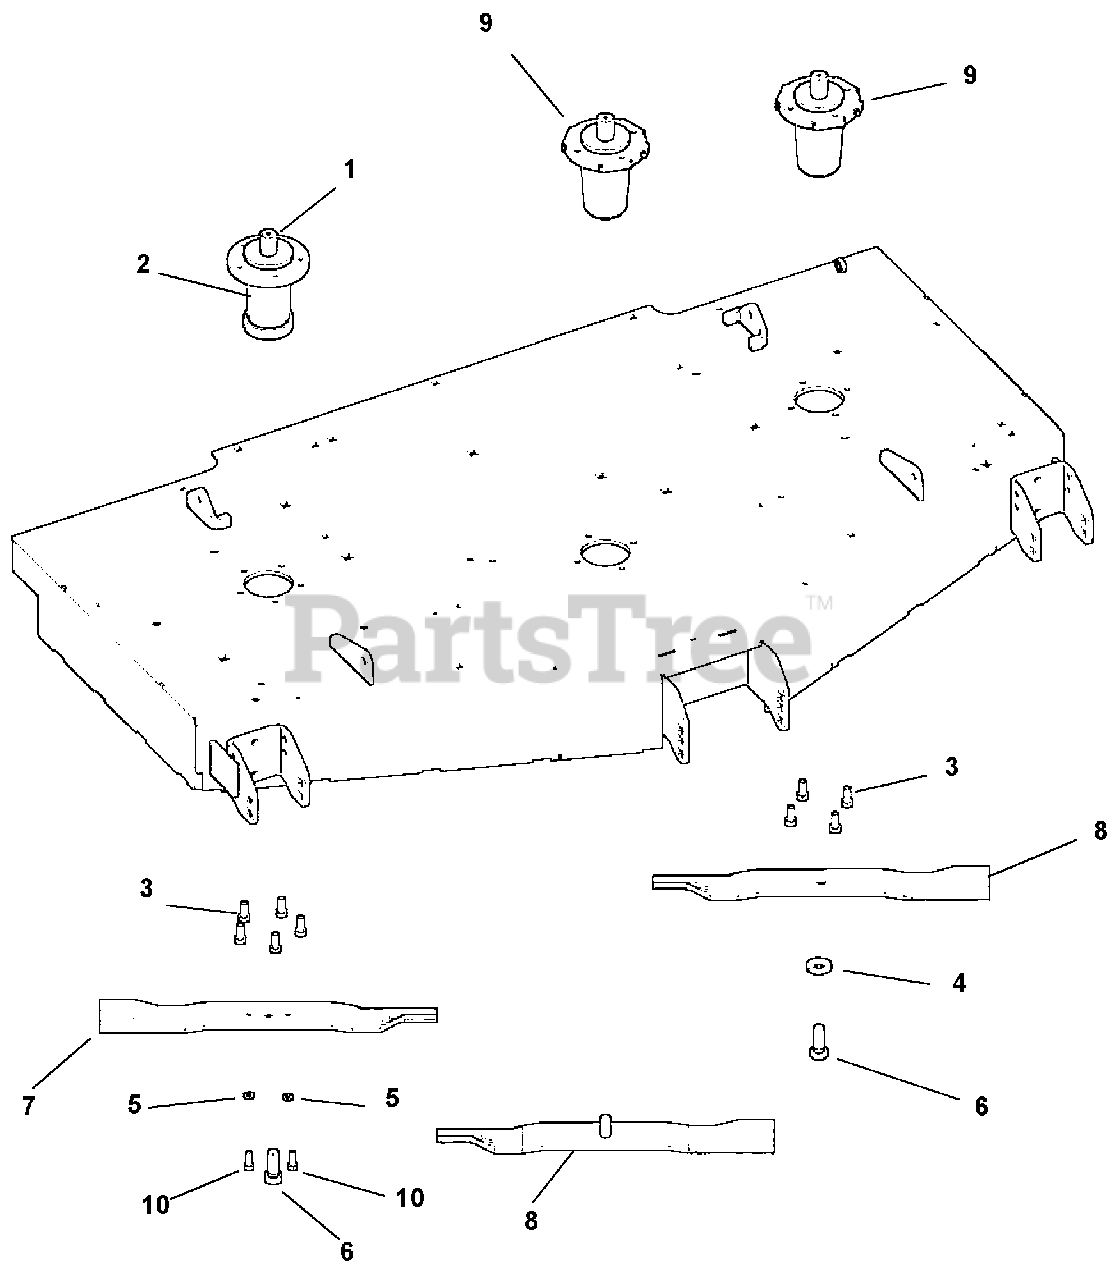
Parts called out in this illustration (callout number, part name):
1	Retainer, Grease
2	Spindle
3	Bolt, Hex .375-16 x 1
4	Washer, Belleville .63 x 1.625 x .14
5	Lock Washer, Spring Regular
6	Bolt, Hex .62-18 x 1.75
7	Blade, 20.83" Mower (Counterclockwise Rotation)
8	Blade, 20.83"
9	Housing, Spindle (G5000)
10	Bolt, Hex .31-18 x 1.00 Grade 5
